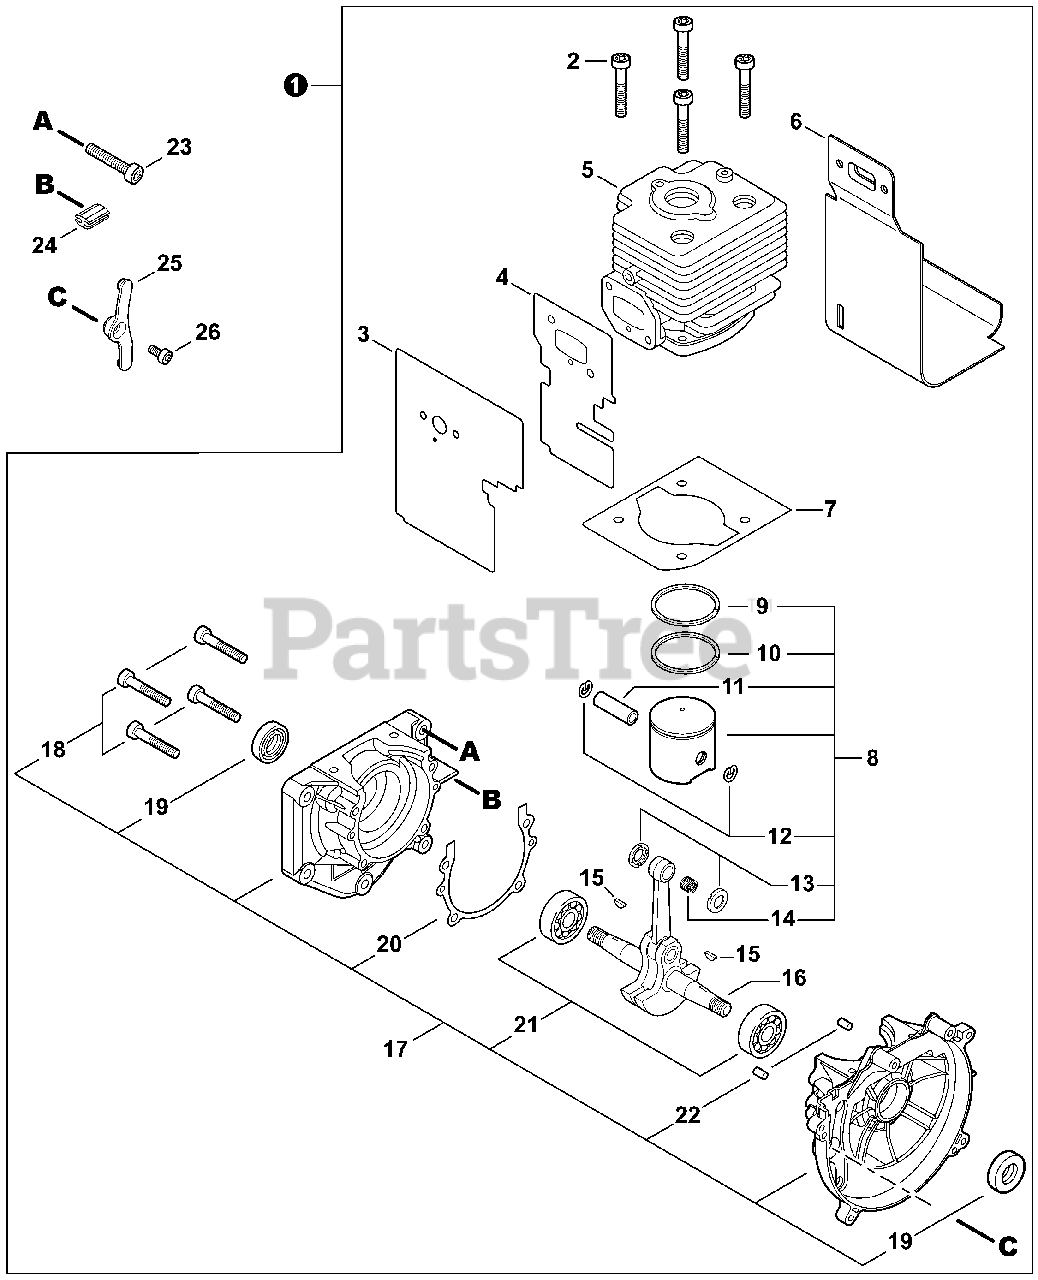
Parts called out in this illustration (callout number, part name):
1	SHORT BLOCK
2	BOLT, TORX 5×25
3	HEAT SHIELD, INTAKE
4	HEAT SHIELD, INTAKE
5	CYLINDER
6	HEAT SHIELD, EXHAUST
7	GASKET, CYLINDER
8	PISTON KIT
9	RING, PISTON
10	RING, PISTON
11	PIN, PISTON
12	RING, SNAP 8
13	WASHER, THRUST
14	BEARING, NEEDLE 10
15	KEY, WOODRUFF 3×14
16	CRANKSHAFT ASSY
17	CRANKCASE KIT
18	BOLT, TORX 5×30
19	SEAL, OIL 15
20	GASKET, CRANKCASE
21	BEARING, BALL 6302
22	PIN, LOCATING 4×8
23	SCREW 6×30
24	COVER, DUST
25	COVER, DUST
26	BOLT, TORX 5×10
